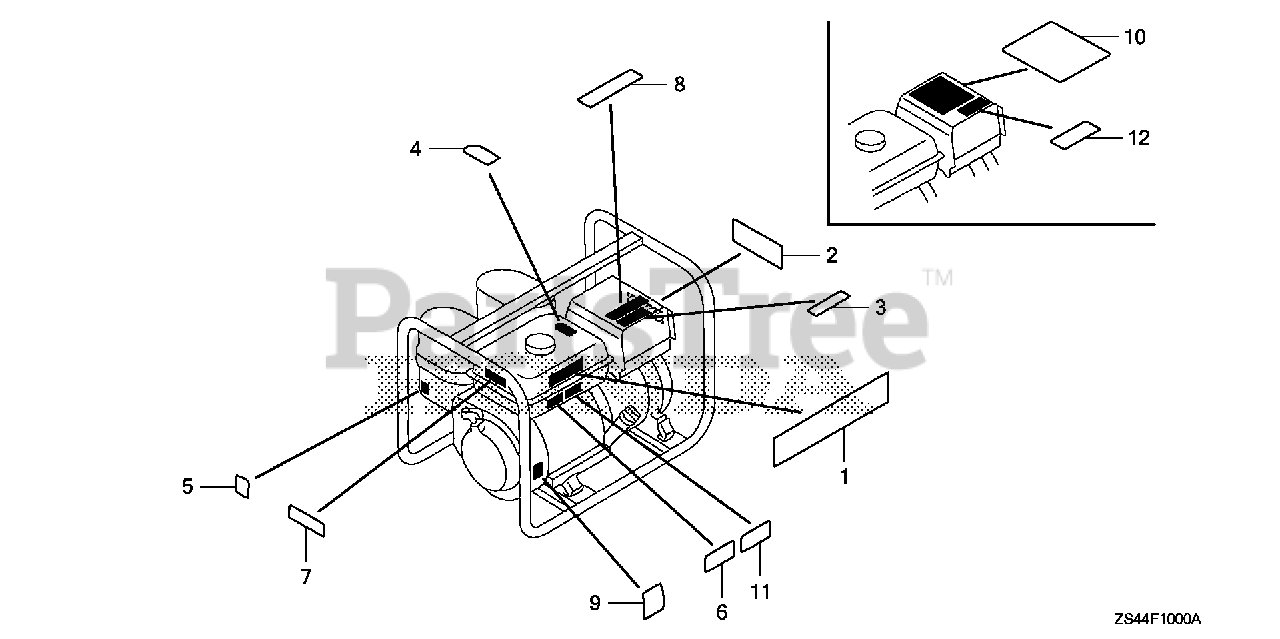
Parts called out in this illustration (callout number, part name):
1	EMBLEM (EZ3500)
2	PLATE, CAUTION (EZ3500) (A)
3	LABEL, RAIN WARNING (ENGLISH)
4	MARK, CAUTION (ENGLISH/FRENCH/SPANISH)
5	MARK, CHOKE (ORANGE)
6	MARK, OIL ALERT (ENGLISH)
7	MARK, CAUTION (ENGLISH/FRENCH/SPANISH)
8	LABEL, CONNECT WARNING (ENGLISH)
9	MARK, OIL CAUTION
